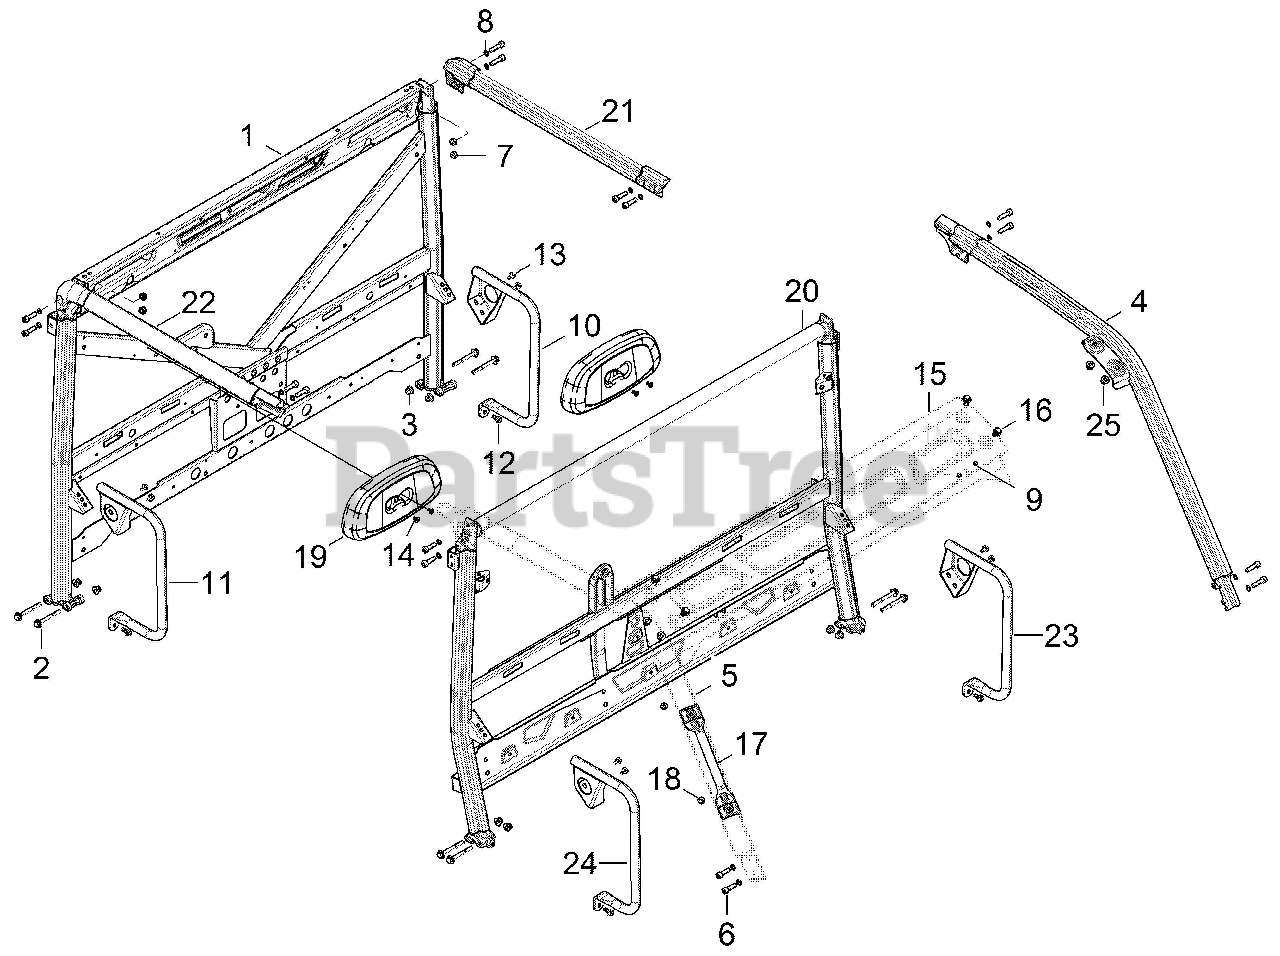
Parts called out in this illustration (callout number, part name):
1	WELD-CAB FRAME,REAR,BLK
2	SCR-HXFL-M10X1.25X80 8.8 ZOD
3	NUT-M10X1.25,FLG,NYLOC-OLIVE D
4	FRONT CAB FRAME, FRONT LH
5	FRONT CAB FRAME, FRONT RH
6	SCR-SH-M10X1.5X35 8.8 ZPB
7	NUT-NYLOC M10X1.5,REF
9	CLIP-PLASTIC,DART
10	HIP BOLSTER, LH
11	HIP BOLSTER, RH
12	SCR-HXFL-M8X1.25X20 8.8 ZOD P3
13	SCR-TXTH-M6X1.0X25 RIE
14	RIVET(50)
15	WINDSHIELD MOUNT PLATE
16	SCREW-HXFL-M10X1.25X20
17	HANDLE-GRAB,ROPS,BLK
18	BOLT-M8X1.25X20,HXFLG,TAP/R-OD
19	HEADREST-GRAVELY,GRAY
20	WELD-CAB FRAME,CENTER 6 PASS
22	WELD-CAB FRAME,REAR,LH,M.BLK
23	WELD-CAB FRAME,REAR,RH,M.BLK
24	HIP BOLSTER FRONT: 219
25	HIP BOLSTER FRONT: 219
26	NUT-M10X1.25,FLG,NYLOC-OLIVE D
